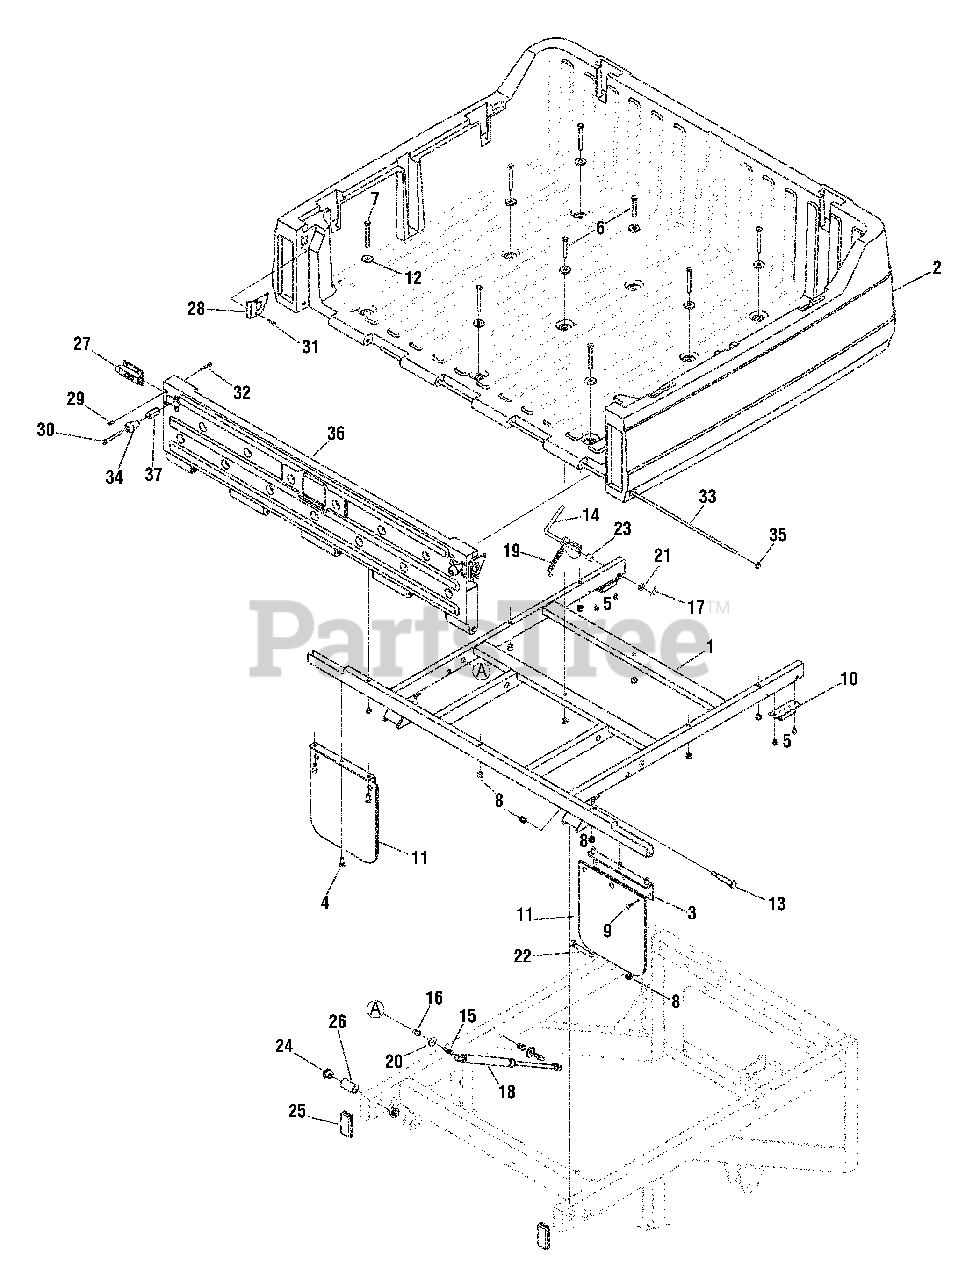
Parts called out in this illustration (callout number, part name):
3	Mud Flap Bracket
4	Hex Screw, 3/8-16 x.75
5	Self Tap Screw, 1/4-20 x.500
6	Hex Screw, 3/8-16 x 2.50
7	Hex Screw, 3/8-16 x 3.25
8	Hex Lock Nut, 3/8-16
9	Pop Rivet
10	Bumper, Suspension
12	Flat Washer,.406 x 1.26 x.17
13	Shoulder Screw, 1/2 x 2.50 Lg.
14	Latch Assembly
15	Ball Stud, 5/16-18
16	Insert Nut. 5/16-18
17	Cotter Pin
18	Gas Spring, 6.91 Stroke
19	Extension Spring
20	Flat Washer,.344 x 1.125 x.12
21	Flat Washer,.406 x.875 x.059
22	Shoulder Bolt, 3/8-16 x.5OD x 2.0
23	Spacer,.385 x.625 x.700
24	Flange Bearing,.51
25	Tubing Plug
26	Leaf Spring Rear Spacer
27	Tailgate Latch Assembly
28	Kick Plate - LH
29	Screw, 10-24 x 5/8
30	Hex Screw, 5/16-18 x 2.75
31	Screw, #12-16 x 1.000
32	Machine Screw, #10-24 x 1.625
33	Tailgate Hinge
34	Knob
37	Spacer,.315ID x.375OD x 2.25
